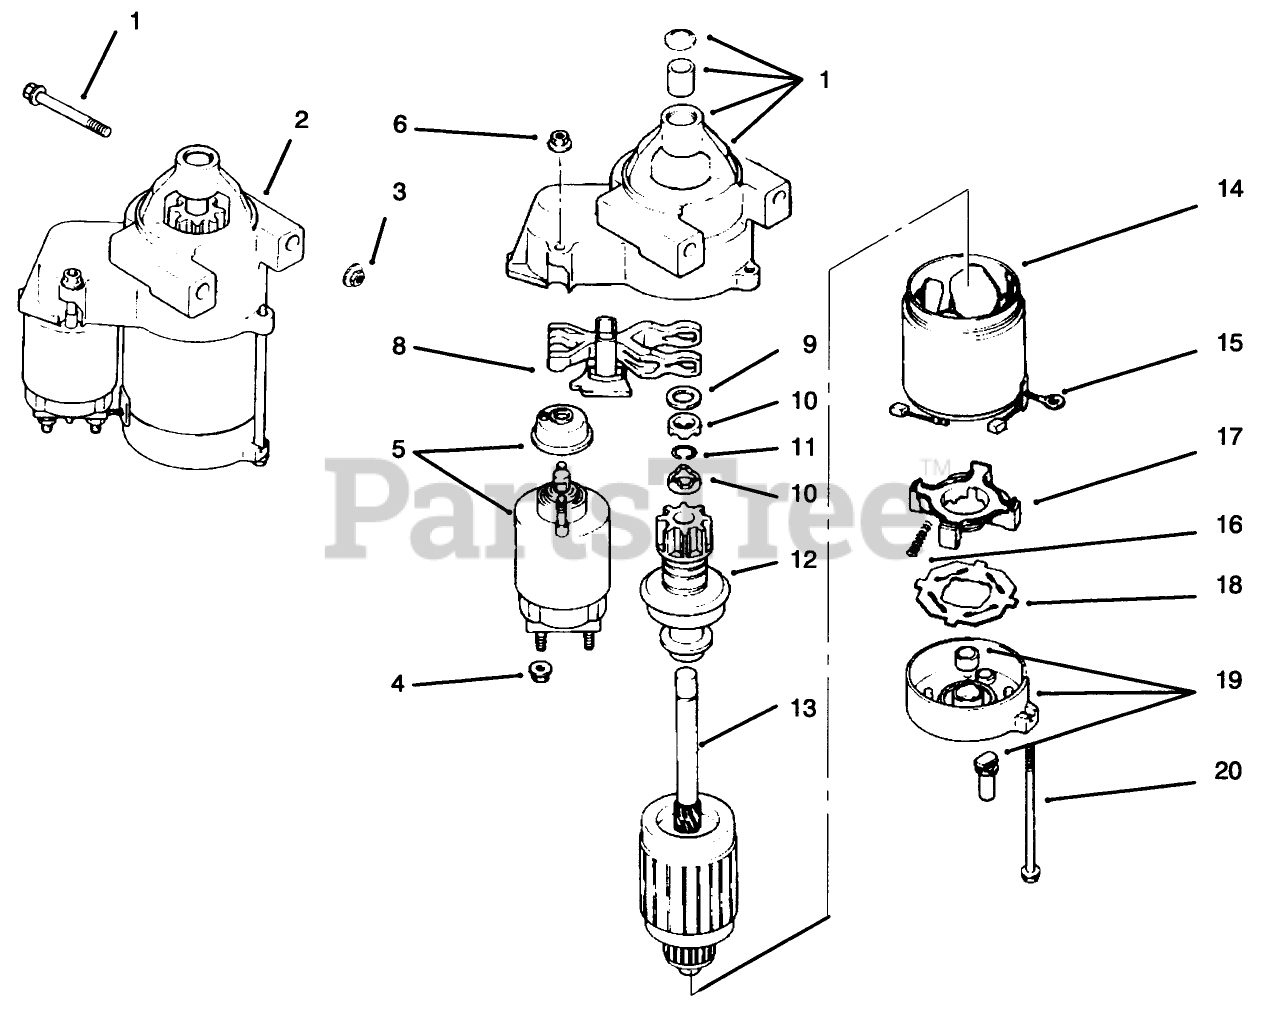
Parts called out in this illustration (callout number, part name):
1	Screw M8x1.25x80 (Only On: 72103, 72083)
2	Starter-Solenoid Shift (Incl. Ref. # 4-20)
4	Nut Starter
5	Cap-Drive End
7	Solenoid
8	Lever Starter Drive
9	Washer-Thrust
10	Nut-Stop Collar
11	Ring-Retainer
12	Drive-Pinion
13	Armature-Starter
15	Kit-Brush (Incl. Ref. # 16)
16	Spring-Brush
17	Holder-Brush
18	Insulator
19	Cap-Commutator End
